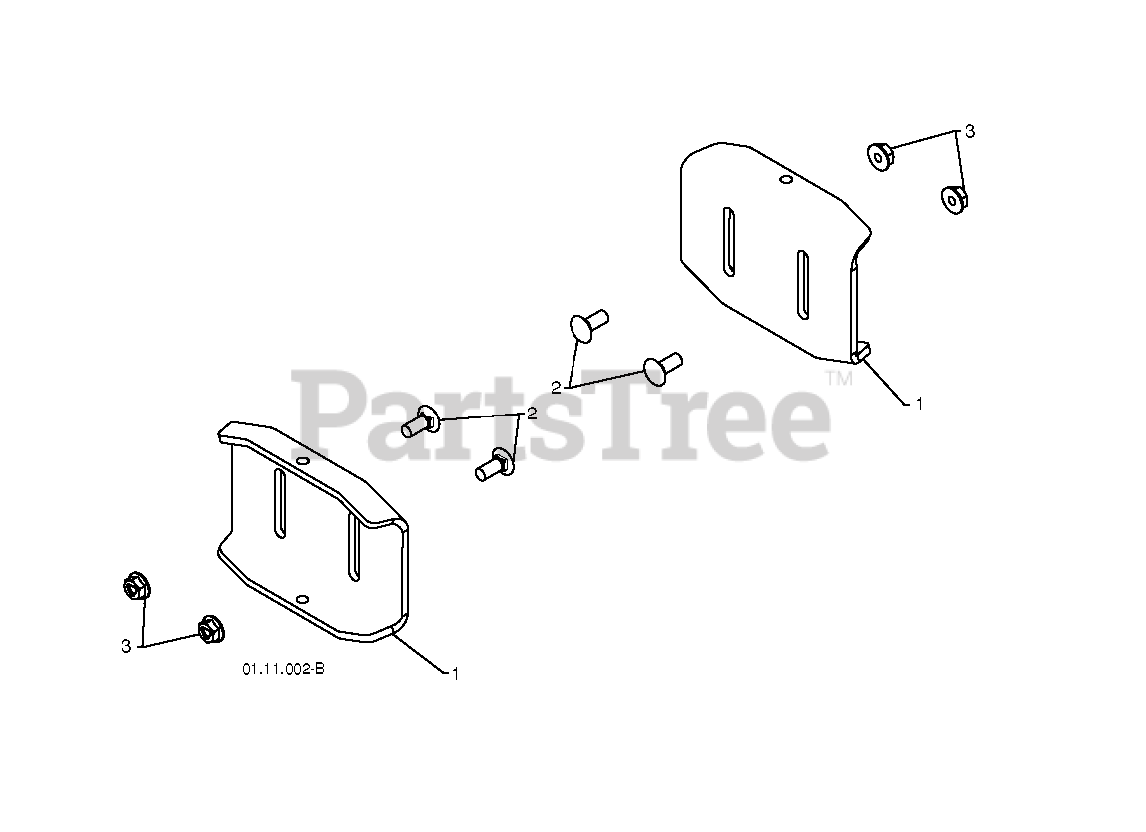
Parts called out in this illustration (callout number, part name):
1	SKID PLATE
2	BOLT
3	NUT.LOCK.5/16-18
